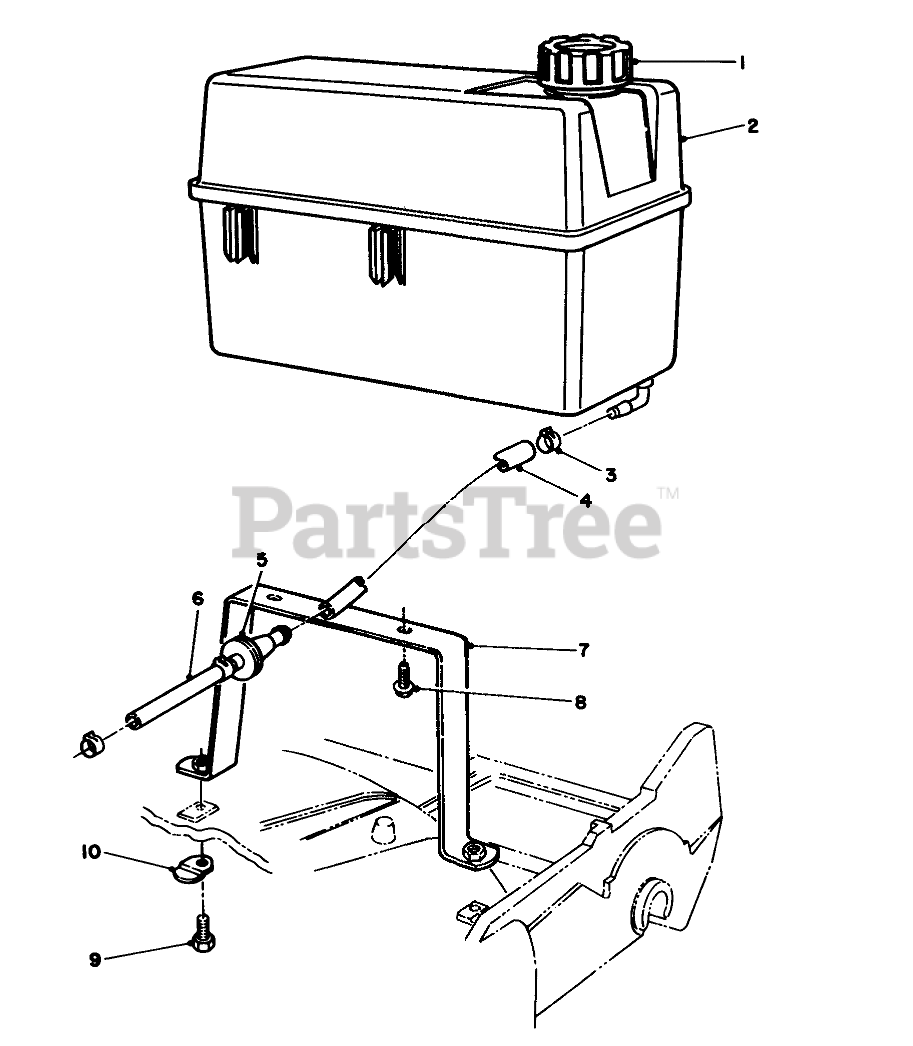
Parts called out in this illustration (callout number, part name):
1	GAS CAP ASM
2	Tank-Gas
3	CLAMP-FUEL LINE
4	HOSE-FUEL
5	FILTER-FUEL
6	HOSE-FUEL
7	Wa-Base
8	SCREW-HWH
9	SCREW-HH
10	SHIELD-RETAINER
